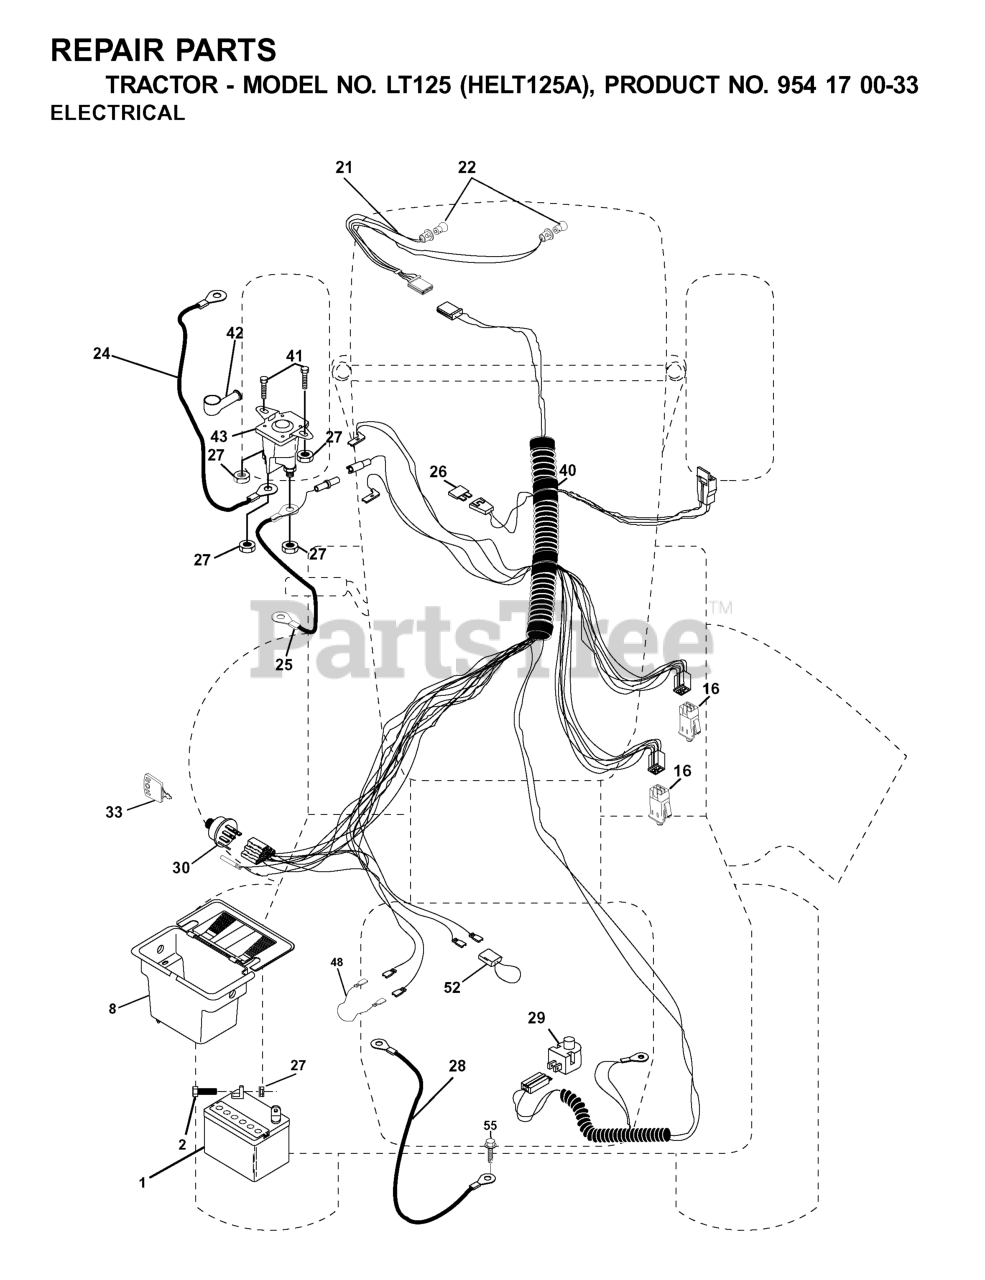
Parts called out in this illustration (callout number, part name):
1	BATTERY 12 VOLT 25 AMP
2	BOLT.HEX.1/4.X.3/4.DICHROMATE
8	CASE BATTERY MECH HINGE
16	SWITCH INTERLOCK
24	BATTERY CABLE GT
25	CABLE BATTERY
26	FUSE 20AMP
27	NUT
28	CABLE T
29	RP.SWITCH.PLUNGER.NC.GRAY
30	IGNITION SWITCH
33	KEY MLD GEN DELTA
40	HARNESS, IGN. LTH120
41	BOLT
42	TERMINAL COVER
43	REPL BY 532 1461-54
48	ADAPTER.AMMETER
52	WIRE PROTECTION LOOP
